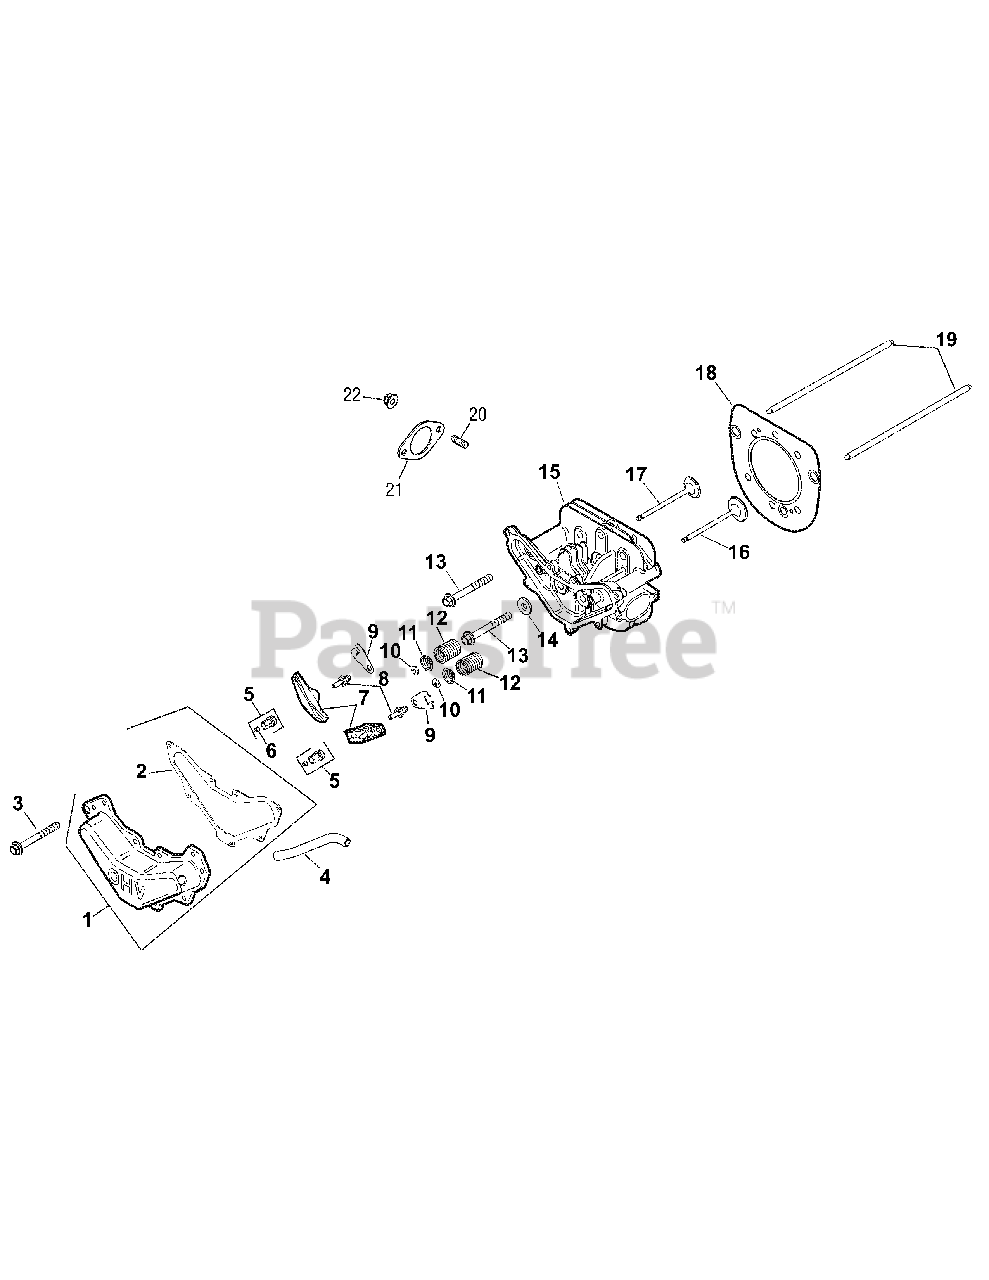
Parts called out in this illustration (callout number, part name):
1	Kit, valve cover (Includes 2)
2	Gasket, valve cover
3	Screw, hex. flange M6x1.0x20
4	Hose, breather
5	Pivot, rocker arm
8	Stud, rocker
9	Plate, push rod guide
10	Lock, retainer
11	Cap, valve spring
12	Spring, valve
13	Screw, hex. flange M10x1.5x37
14	Washer, flat 1/2"
15	Head, cylinder
16	Valve, exhaust
17	Valve, intake
18	Kit, head gasket
19	Rod, push
20	Stud, exhaust
22	Nut, hex flange M8x1.25
